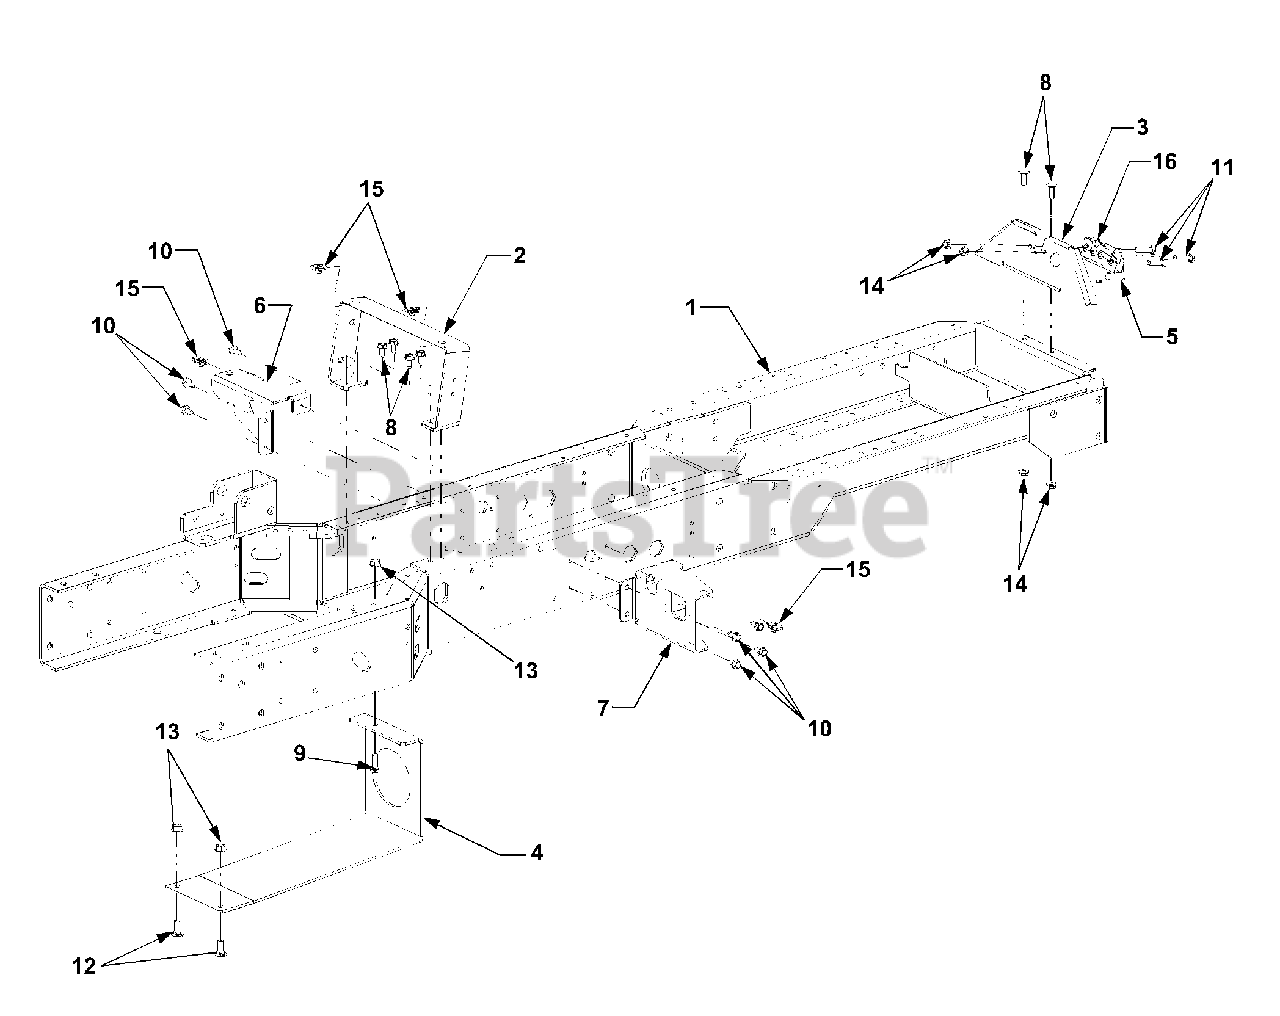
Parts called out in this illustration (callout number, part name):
9	Screw, Hex Cap, 3/8-16 x 1.0 GR5
10	Screw, Hex Wash. Hd., 5/16-18 x .75
11	Screw, Hex Cap, 5/16-18 x 1.375 GR5
12	Screw, Carriage, 3/8-16 x 1.0
13	Nut, Hex Flange Lock, 3/8-16
14	Nut, Hex Flange Lock, 5/16-18
15	Nut, U Speed, 5/16-18
16	Latch, Hood
